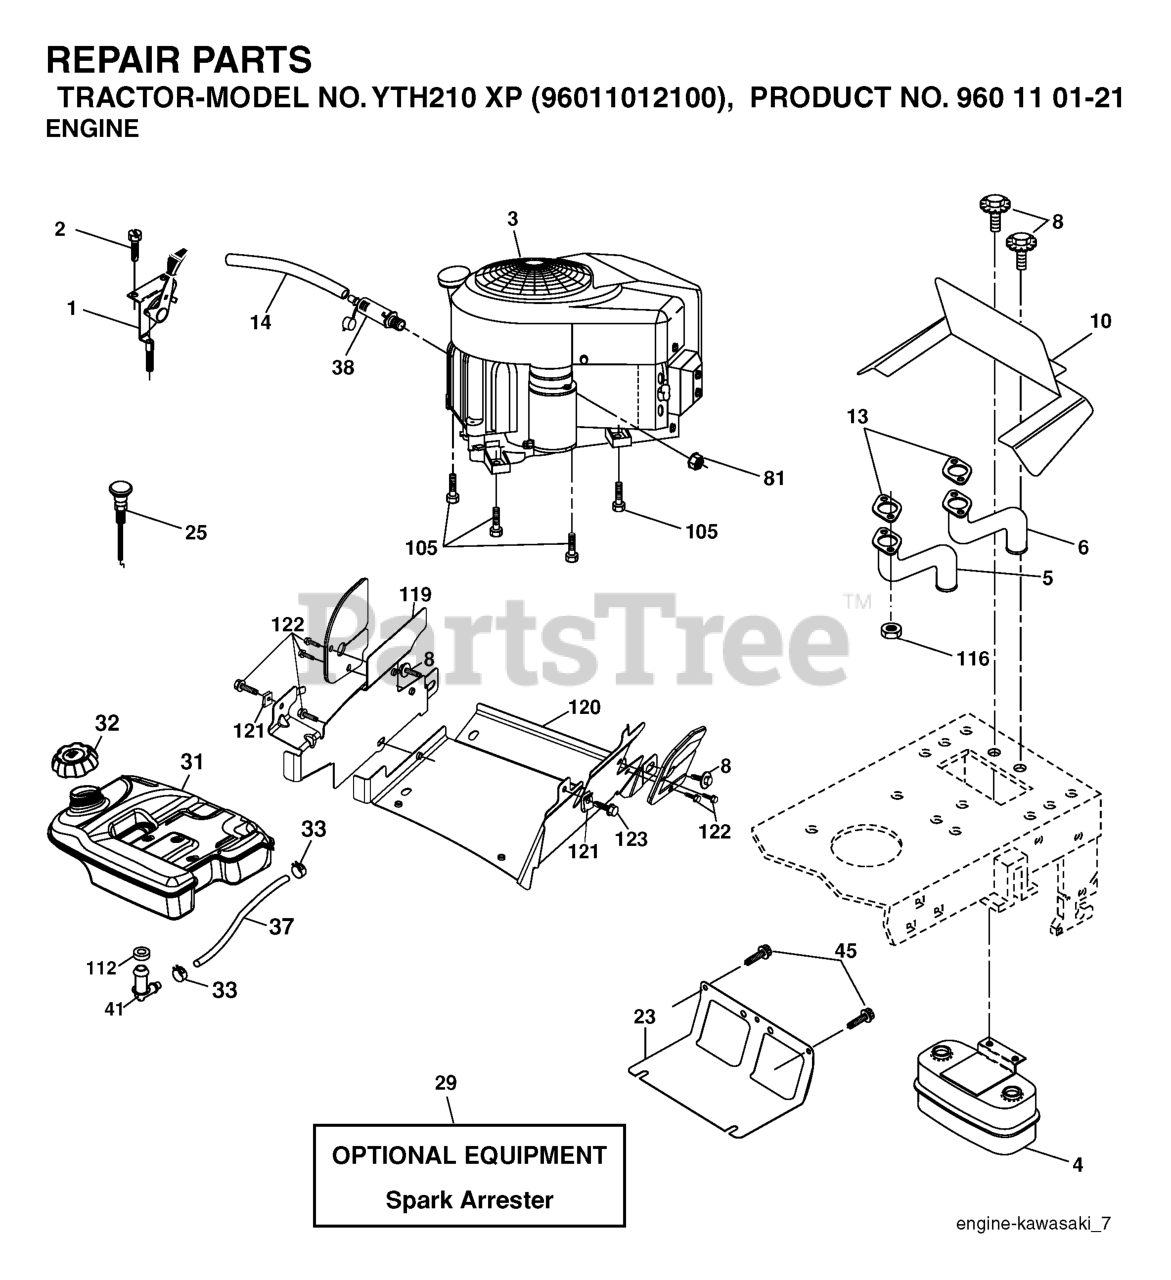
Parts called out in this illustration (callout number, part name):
2	SCREW
4	MUFFLER.TWIN.CYL.LOW.TONE
5	TUBE EXHAUST LH
6	EXHAUST.TUBE.RH.KAWA
8	BOLT.5/16-18UNCX3/4 W/SEMS.BLK
10	RP SHIELD HEAT MUFFLER
14	TUBE, DRAIN OIL ASM.
23	SHIELD.BROWNING.DBR.GUARD
25	CONTROL, CHOKE, 37", PUSH
29	KIT.SPARK ARRESTOR 794945 B&S
31	4.0 REAR FUEL TANK
32	TANK CAP
33	HOSE CLAMP
37	REPL BY 532 00 85-43
41	STEM FUEL TANK
45	SCREW, 3/8-16X3/4
81	NUT
105	SCREW 3/8-16X1
112	BUSHING OUTLET T
116	NUT.HEX.FLANGE.TOPLOCK
122	SCREW.1/4-20X5/8
123	SCREW, 5/16-18 X 1/2
